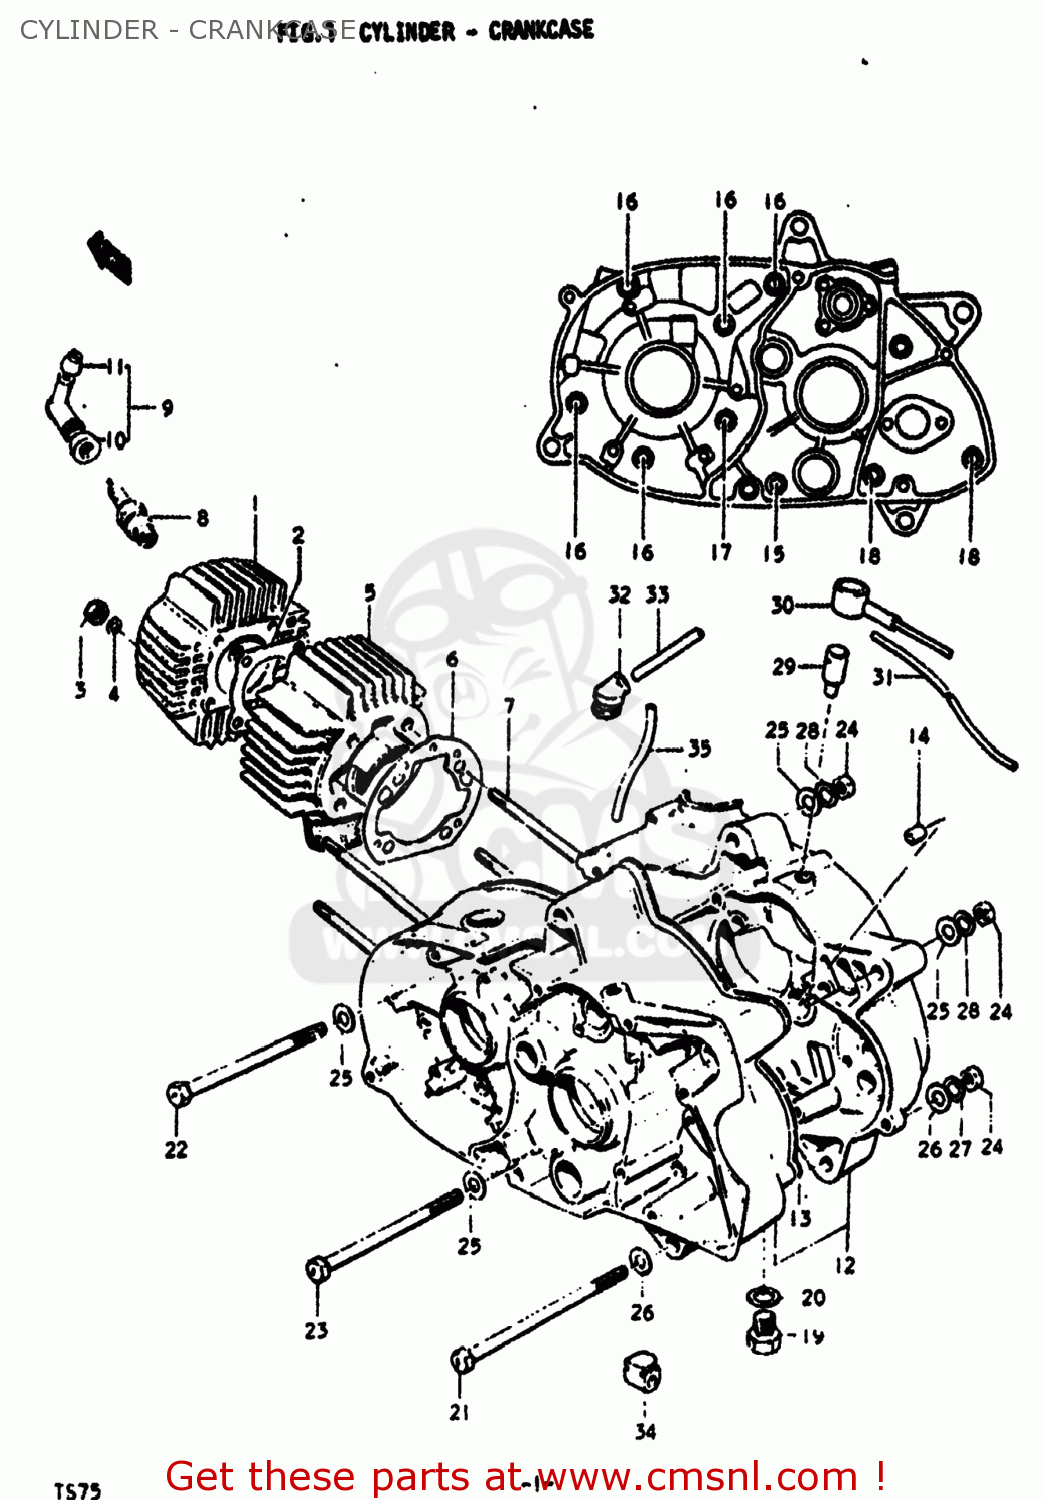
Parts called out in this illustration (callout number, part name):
1	HEAD,CYLINDER
2	GASKET,CYLINDER HEAD (NAS)
3	NUT
4	LOCK WASHER
5	CYLINDER
6	GASKET,CYLINDER (MCA)
7	BOLT,STUD
8	SPARK PLUG
9	CAP,SPARK PLUG
11	SEAL,SPARK PLUG
12	CRANKCASE SET
13	GASKET,CRANKCASE (MCA)
14	PIN
15	SCREW
16	SCREW (6X45)
17	SCREW
18	SCREW
19	PLUG
20	GASKET(10X14X3.6) (NAS)
21	BOLT 8X110
22	BOLT 8X105
23	BOLT 8X100
24	NUT
25	WASHER
26	WASHER
27	WASHER,LOCK,8.
28	LOCK WASHER
29	PLUG,TRANSMISSION BREATHER
30	PLUG,BREATHER
31	HOSE
32	GROMMET
33	HOSE
34	GROMMET
35	HOSE
